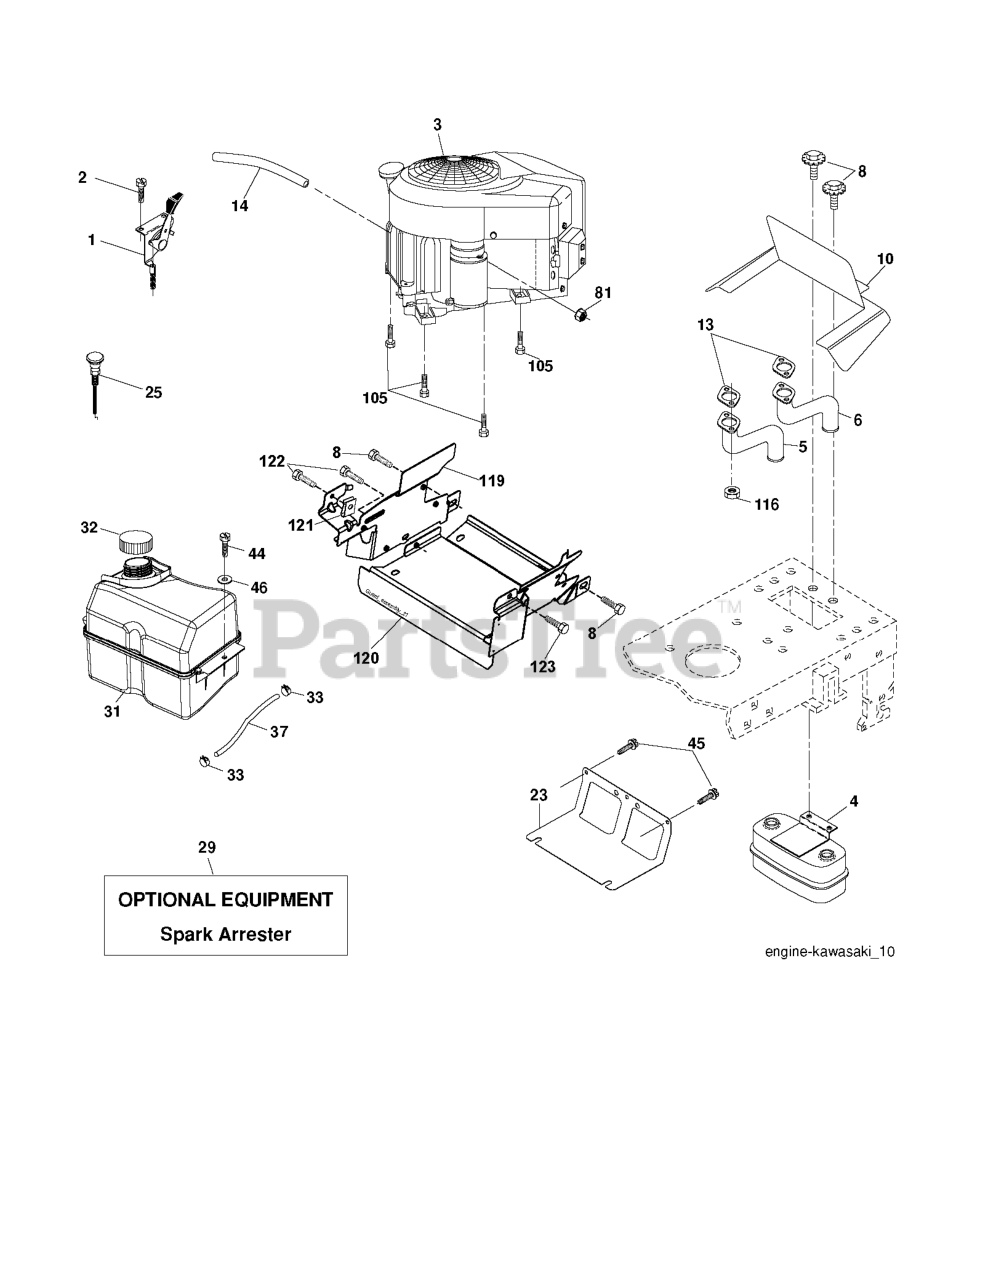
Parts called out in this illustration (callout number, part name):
1	CONTROL.THROTTLE.COBRA.BLACK
2	SCREW
4	MUFFLER.TWIN.CYL.LOW.TONE
5	EXHAUST TUBE LH KAWI
6	EXHAUST TUBE RH KAWI
8	BOLT.5/16-18UNCX3/4 W/SEMS.BLK
10	RP SHIELD HEAT MUFFLER
14	TUBE, DRAIN OIL ASM.
23	SHIELD.BROWNING.DBR.GUARD
25	CONTROL.CHOKE.ERGO.PUSH-IN.BLA
29	KIT.SPARK ARRESTOR 794945 B&S
31	RP TANK FUEL FRT 1.5 GAL
32	FUEL CAP
33	HOSE CLAMP
37	LINE.FUEL.20
44	SCREW HEXWSHR 1/4-20X3/4
45	SCREW, 3/8-16X3/4
81	NUT
105	SCREW 3/8-16X1
116	NUT.HEX.FLANGE.TOPLOCK
119	LENKRAD
120	GUARD 532199767
122	SCREW.1/4-20X5/8
123	SCREW, 5/16-18 X 1/2
